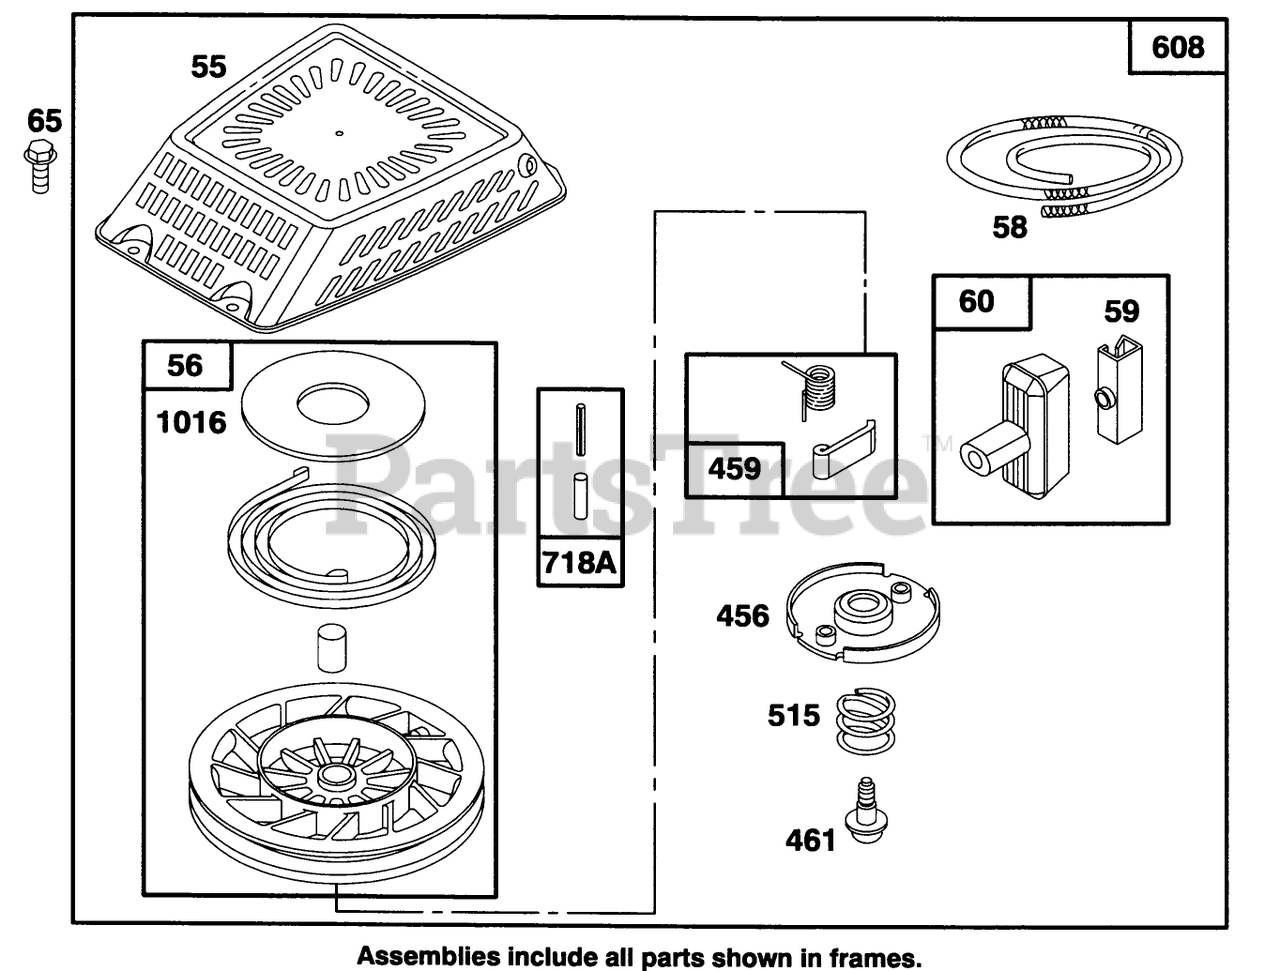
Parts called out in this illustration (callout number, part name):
58	Rope-Starter (Cut To Suit)
60	HANDLE-REWIND STARTER
456	RETAINER - SPRING
515	SPRING - RETAINER
